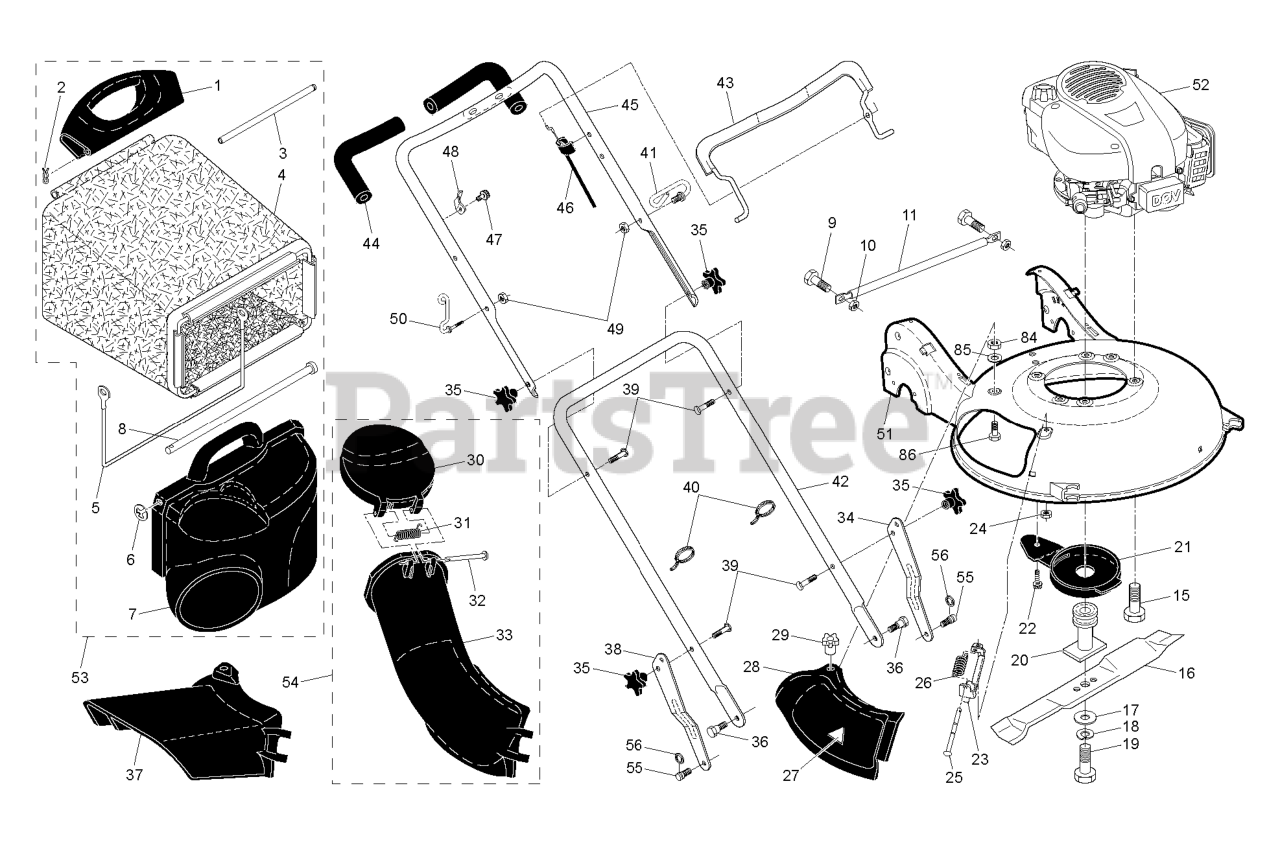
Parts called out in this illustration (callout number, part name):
1	HANDLE.GRASSBAG.REAR.H-GRAY
2	COTTER PIN (3 2)(2 2MC)
3	ROD.REAR.HANDLE.YELLOW
5	FRAME, GRASSBAG
7	DOOR, GRASSBAG
8	ROD, PIVOT
10	LOCKNUT.NYLOC.1/4-20
11	TUBE, REAR SKIRT
15	BOLT 3/8-16X1-1/8
16	Blade, 21"
17	WASHER,HARDEN
18	LOCKWASHER
19	BOLT.HD.HEAD.3/8-24X2.50 (2 2)
20	ADAPTER.BLADE
21	DEBRIS SHEILD
22	SCREW 1/4X20
23	BRACKET.ASM.HINGE
24	NUT.HEX.FLANGE.1/4
25	ROD.HINGE.1/4"3.82"
26	SPRING.MULCH.DOOR
27	DECAL.INTERNATIONL.CUTFINGER
28	MULCHER DOOR
29	KNOB.MULCH.DOOR
30	CHUTE.DOOR.21.HV.H-GRAY
32	ROD.HINGE.1/4"3.82"
33	DISCHARGE CHUTE PLASTIC
34	ADJUSTMENT BRACKET, LOWER LH
35	KNOB.HANDLE.PLASTIC.STAR.BLACK
36	SCREW.5/16X.680.TRIM.H
37	GUARD.CLIP.ON.21.HV.GRAY
38	BRACKET.ADJ.LOWER.HDL.RT.GREY
39	BOLT, HANDLE 5/16-18X1.75
40	TIE GUIDE
42	HANDLE.LOWER.GREY
43	BAIL CONTROL
44	GRIP.HANDLE.FOAM.WIDE.(1 SIDE)
45	HANDLE.ASM.UPPER.W/GRIP
46	CABLE.MZR.SNAP-IN
48	BRACKET
49	NUT
50	GUIDE.ROPE.WALK.MOWER
51	Kit, Housing
53	Grassbag Assembly, Complete
54	CHUTE.LOWER.ASM.WALK.MOWER
55	STUD.SHOULDER.T45.BZP
56	E-RING 7/16 RE
84	NUT, HEX
85	LOCKWASHER
86	BOLT.CARRIAGE.1/4-20 X 7/8
